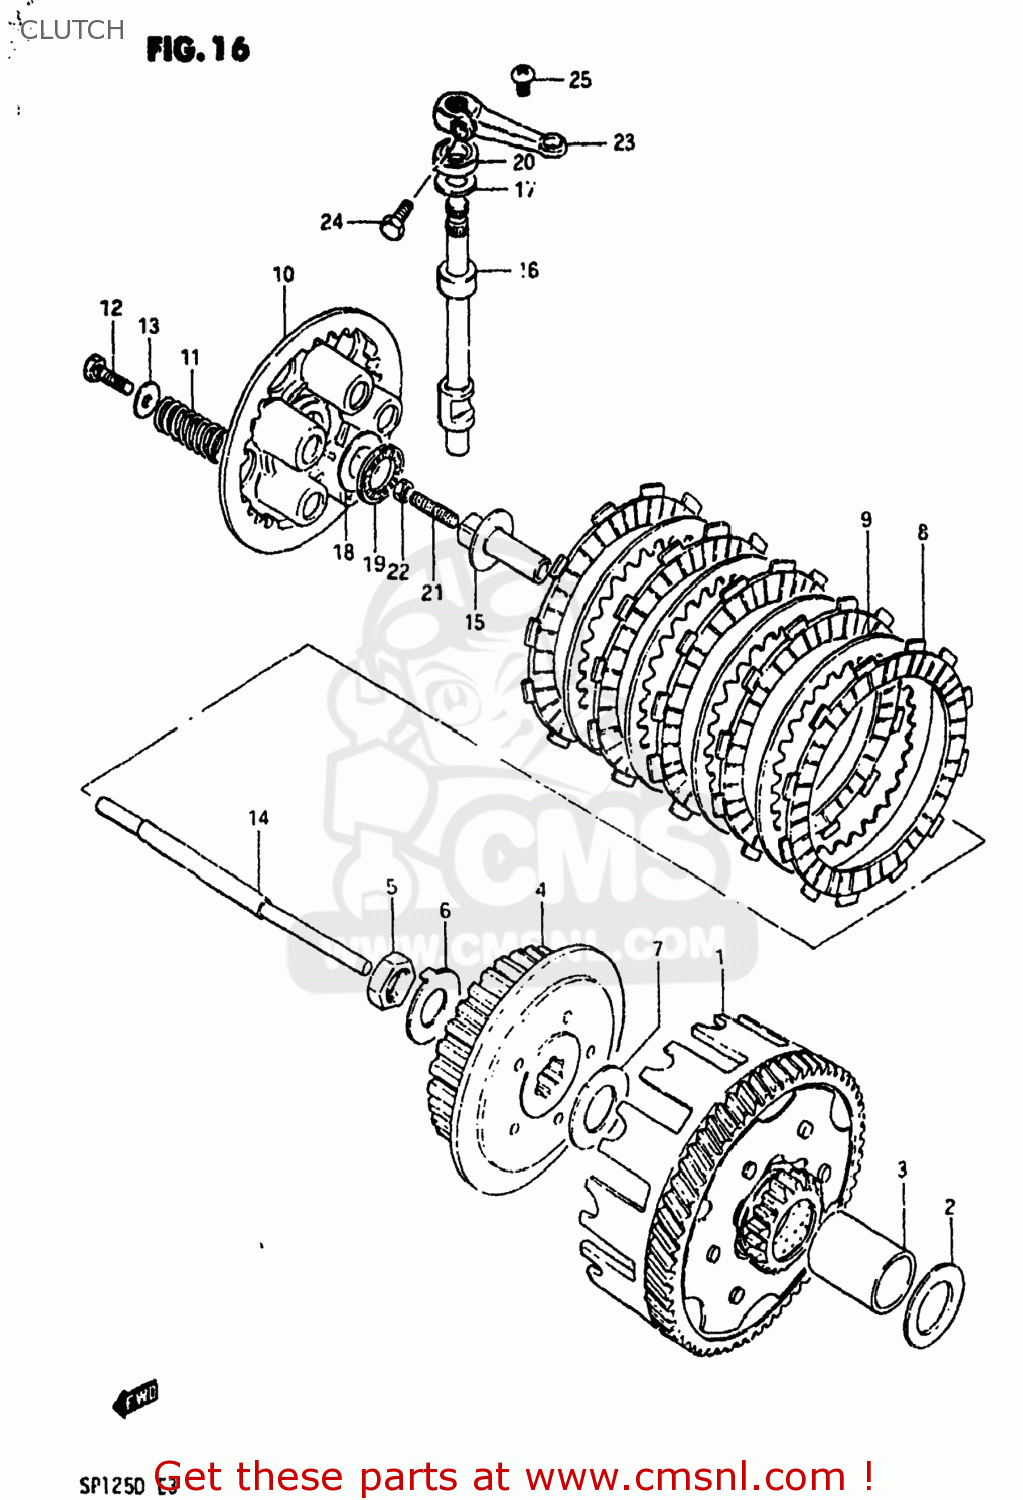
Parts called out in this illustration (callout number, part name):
1	GEAR ASSEMBLY,PRIMARY DRIVE
2	WASHER
3	SPACER
4	HUB,CLUTCH SLEEVE
5	NUT
6	WASHER
7	WASHER
8	PLATE,CLUTCH DRIVE
9	PLATE,CLUTCH DRIVEN (NAS)
10	PLATE,CLUTCH PRESSURE
11	SPRING
12	BOLT(5X16)
13	WASHER (5.5X16X1.2)
14	ROD,CLUTCH PUSH
15	PIECE,CLUTCH PUSH
16	CAMSHAFT,CLUTCH RELEASE
17	WASHER,THRUST
18	WASHER
19	BEARING(15X28X2)
20	OIL SEAL
21	SCREW
22	NUT 6MM
23	ARM,CLUTCH RELEASE
24	BOLT, UPPER
25	SCREW
